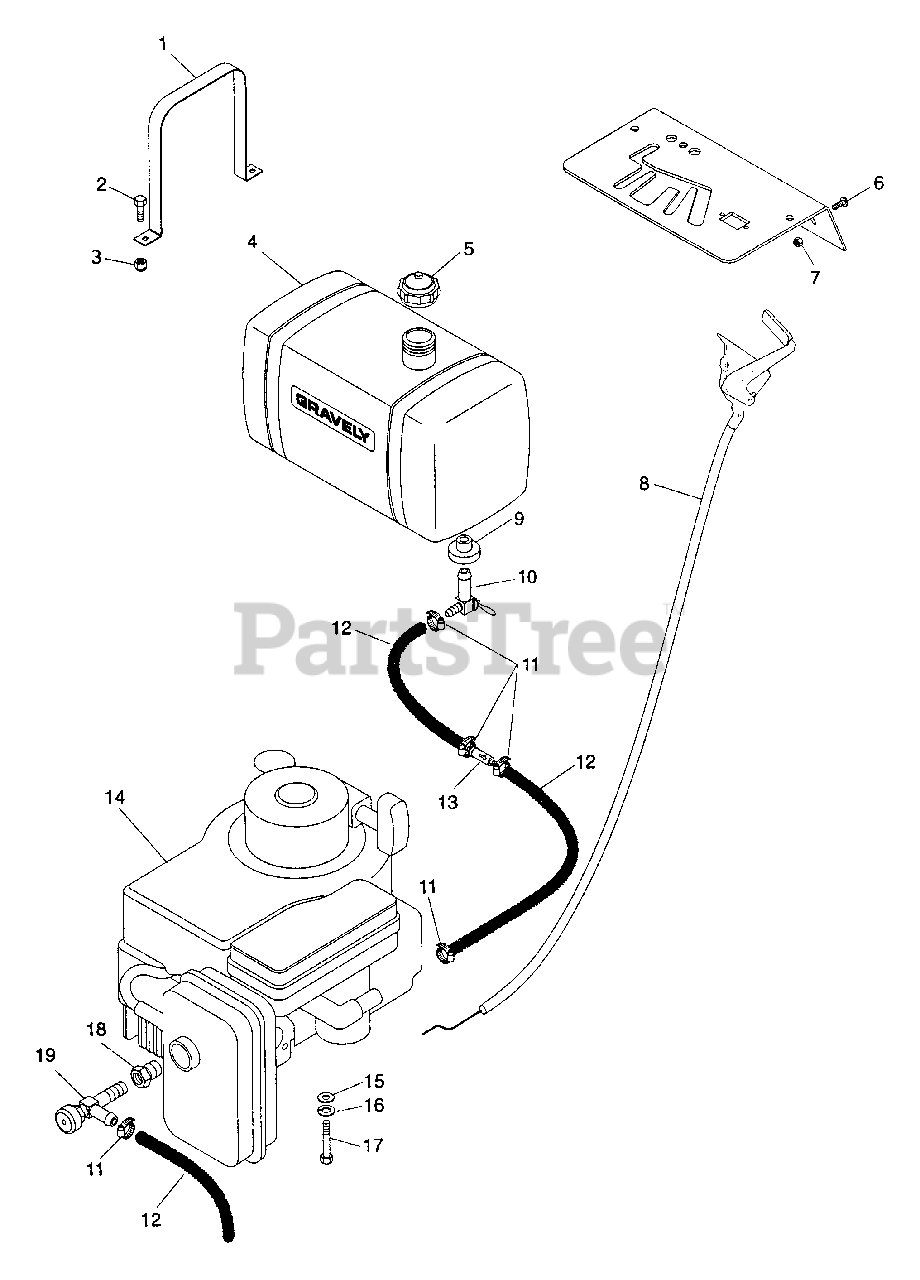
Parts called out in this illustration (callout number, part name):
1	Strap, Fuel Tank
2	Bolt-Hex.25-20 x .63
3	Nut-Locking-Nylon .250-20 Grade 2
4	Tank, Fuel Gravely Pro
5	Cap, Fuel Tank
6	Screw-Machine 10-32 x .50
7	Nut-Locking 10-32
8	Assembly Throttle Control/Cable
10	Valve, Ball Shut-Off
11	Hose Clamp
12	Gas Line-Bulk
13	Filter, Fuel
14	Engine, Kawasaki 12.5 HP
14	Engine, 14 HP, PS-1411
14	Engine - 14 HP Kawasaki OHV
14	Engine - 15 HP Kohler Command
15	Washer-Flat-Steel .344 x .688 x .065
16	Washer-Lock .313 x .078
17	Bolt-Hex M8 x 1.25 x 30mm
18	Adapter, Oil Drain
19	Cock, Oil Drain
